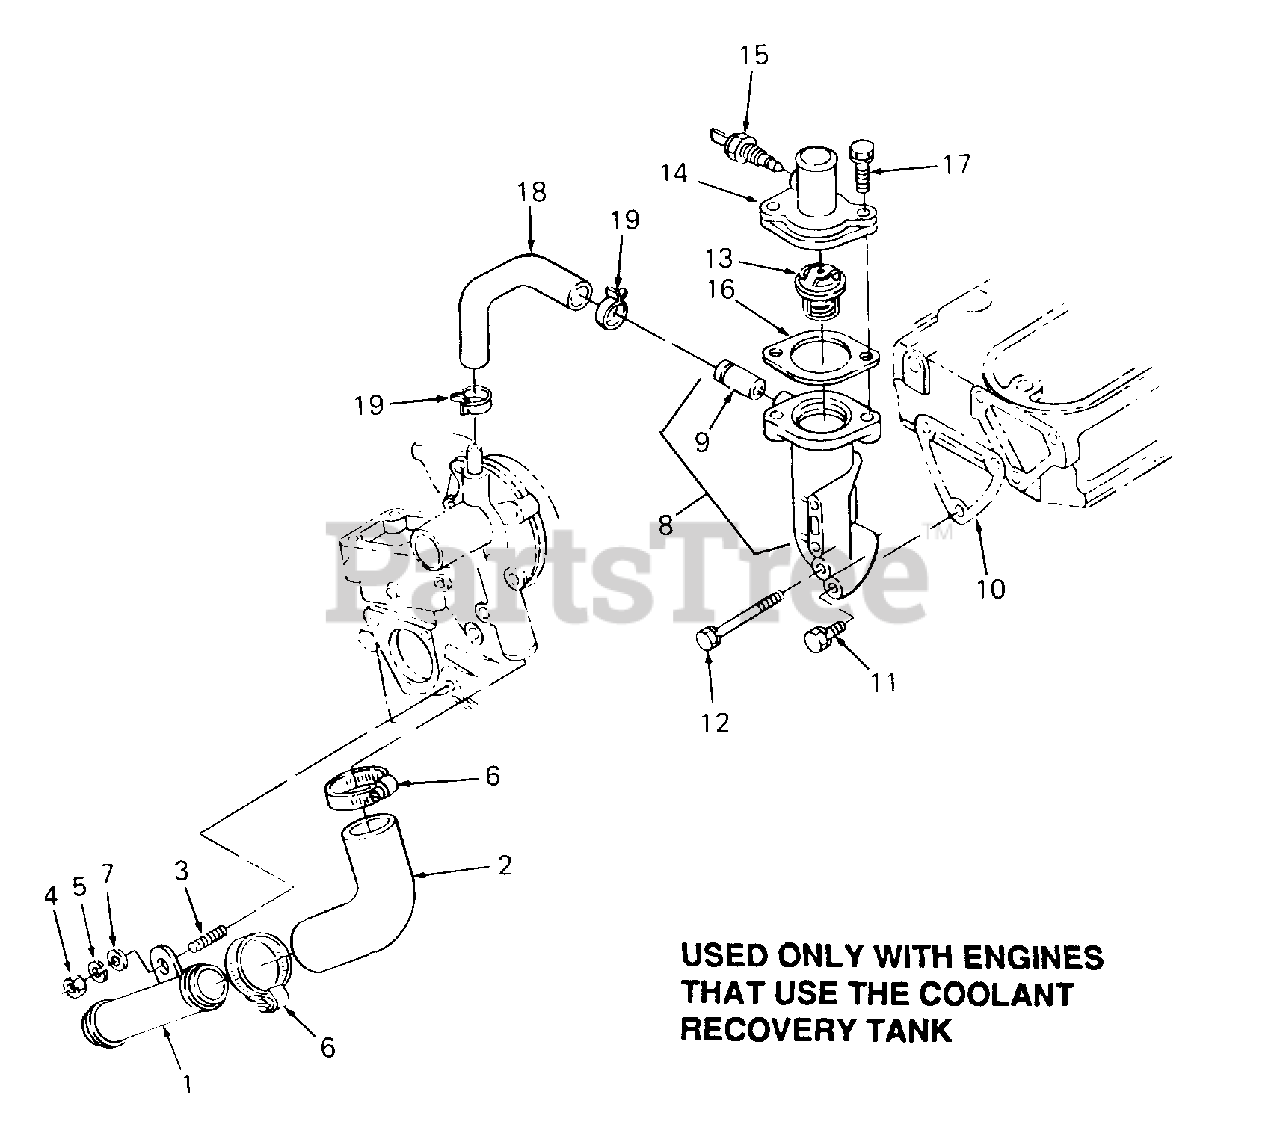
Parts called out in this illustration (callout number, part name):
5	Washer, Spring
7	Washer, Plain
8	Flange, Water (Includes Ref No. 9)
9	Pipe, Water Return
10	Gasket, Water Flange
13	Thermostat Assy
14	Cover, Thermostat
16	Gasket
18	Pipe, Water Return
